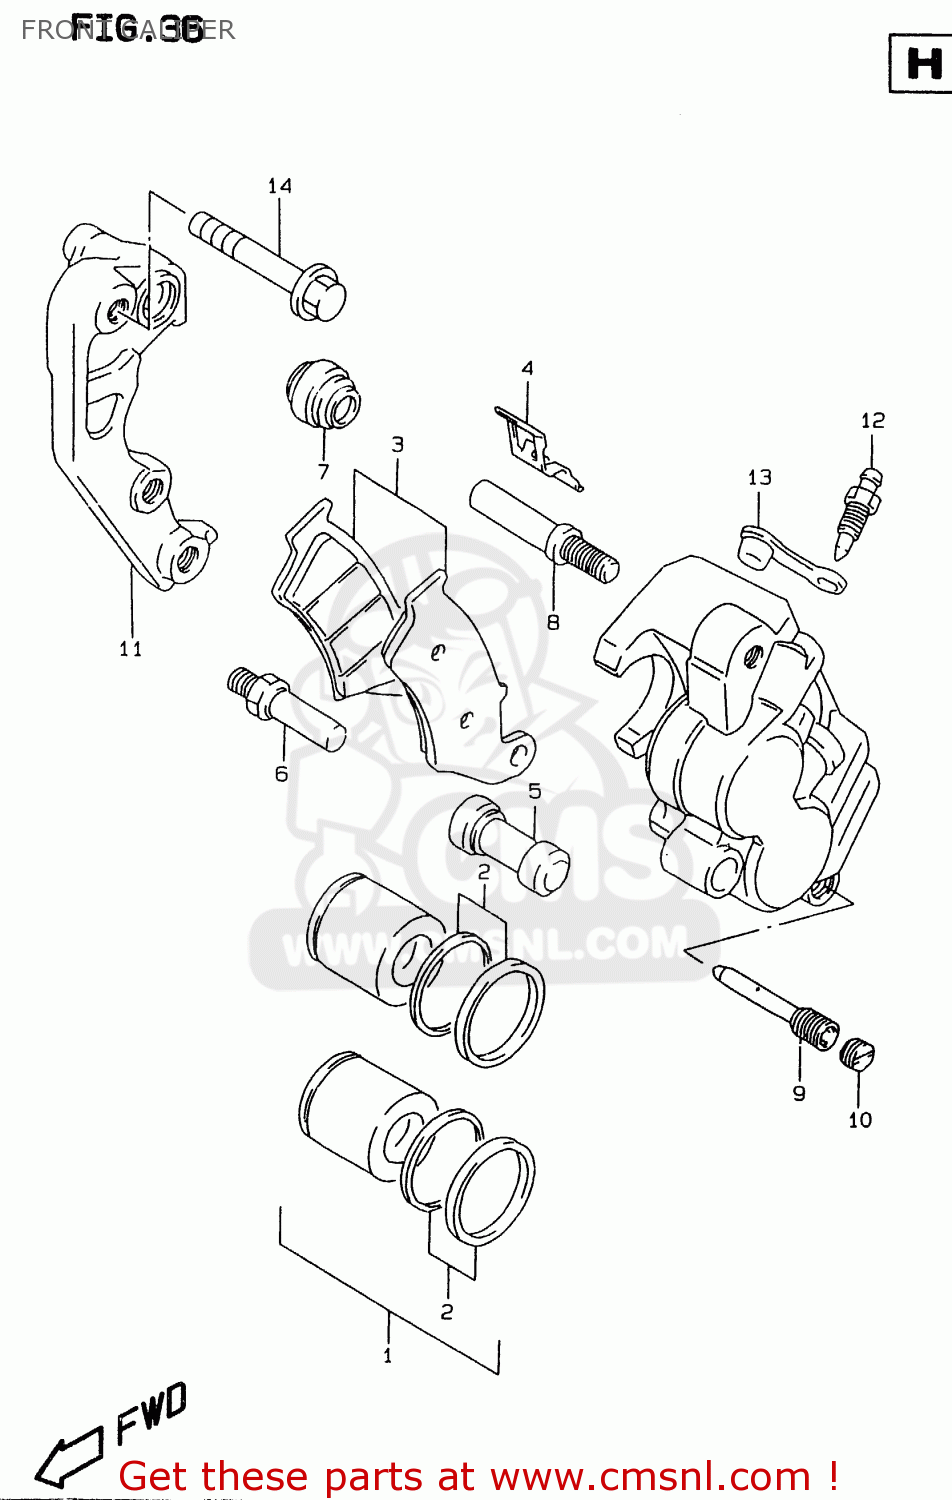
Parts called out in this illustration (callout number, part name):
1	PISTON SET
2	SEAL SET,PISTON
3	PAD SET (NAS)
4	SPRING,PAD
5	BOOT
6	PIN,BOLT
7	BOOT
8	PIN
9	PIN,HANGER
10	PLUG,PIN
11	BRACKET
12	BLEEDER
13	CAP,BLEEDER
14	BOLT(8X40)
